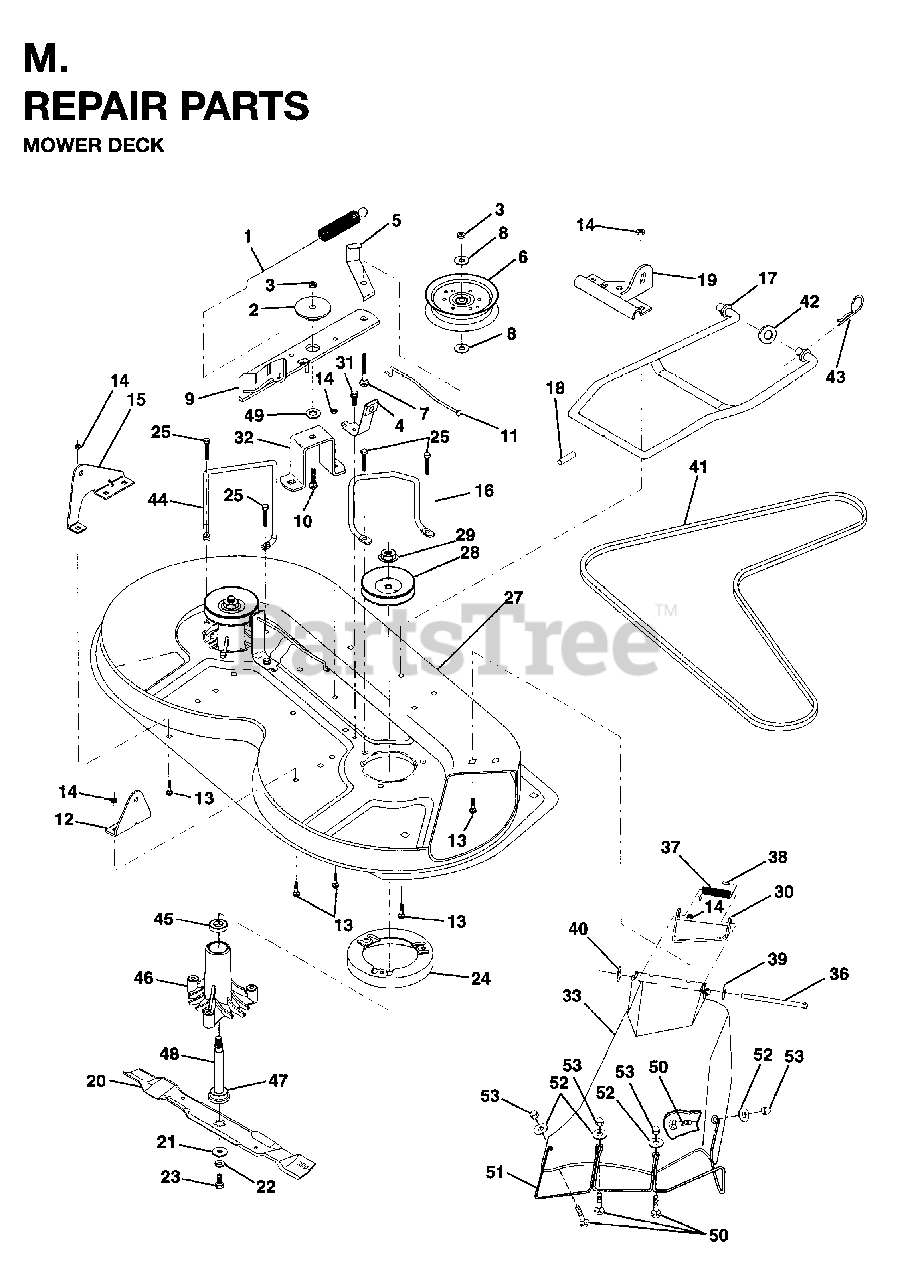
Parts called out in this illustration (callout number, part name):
1	SPRING-MOWER CLUTCH
2	SPACER RETAINER
3	LOCKNUT
4	BRAKE ASSEMBLY
5	IDLER BELT GUIDE
6	PULLEY IDLER
7	BOLT
8	WASHER
9	IDLER ARM ASSY
10	BOLT.3/8-14X1.25
11	BRAKE ROD
12	BRKT LIFT REAR
13	BOLT
14	LOCKNUT
15	BRKT LIFT REAR LH
16	KEEPER RH
17	MOWER LINK STABILIZER
18	PIN GROOVE
19	BRKT LINK STABILIIZER
20	BLADE, HI-LIFT 36" PREMIUM
21	WASHER.BLADE
22	WASHER, LOCK 3/8
23	BLADE BOLT
24	STRIPPER
25	SCREW
26	WASHER
27	MOWER HOUSING
28	PULLEY
29	NUT
30	BRACKET ASM DEFLECTOR
32	SUPT,IDLER ARM
33	DEFLECTOR
36	HINGE ROD
37	SPRING TORSION
38	CAP-SLEEVE LT
39	WASHER - 15X7.3X1.6
40	NUT PUSH M
42	WASHER - M12
43	SPRING RETAINER
44	KEEPER LH
46	HSG MANDREL
47	BEARING
48	SHAFT ASM VENT
49	HARDENED WASHER
50	SCREW
53	NUT
